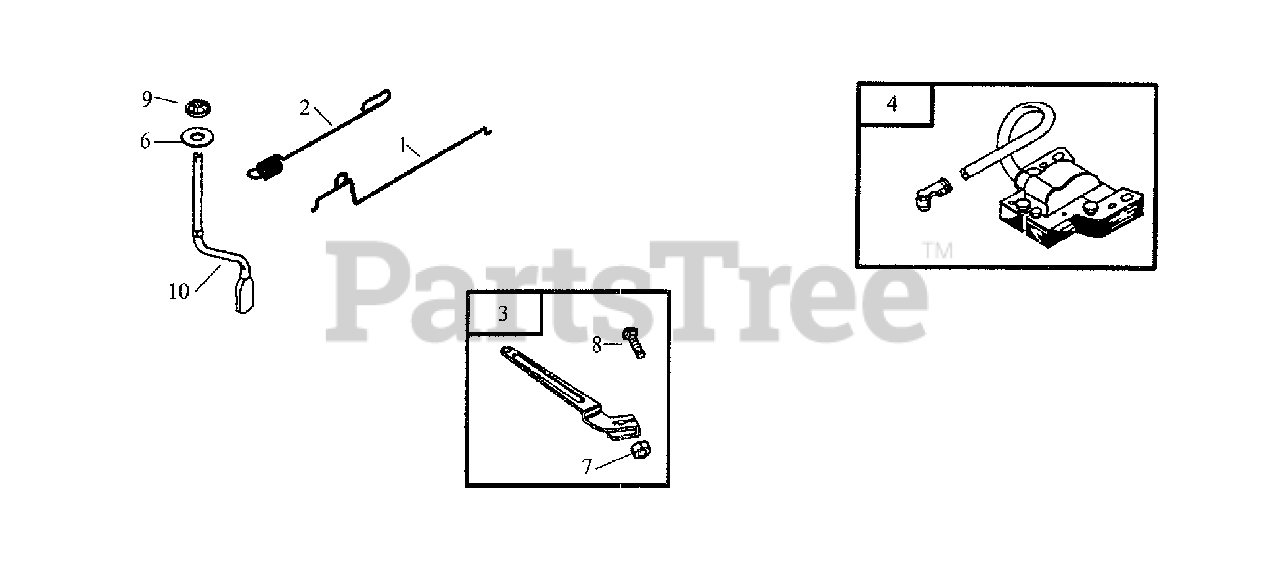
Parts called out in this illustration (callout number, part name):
1	Link, Governor
2	Governor Spring
3	Lever, Control
4	Armature, Magneto
8	Bolt
9	Shaft Retainer
10	Crank, Governor
